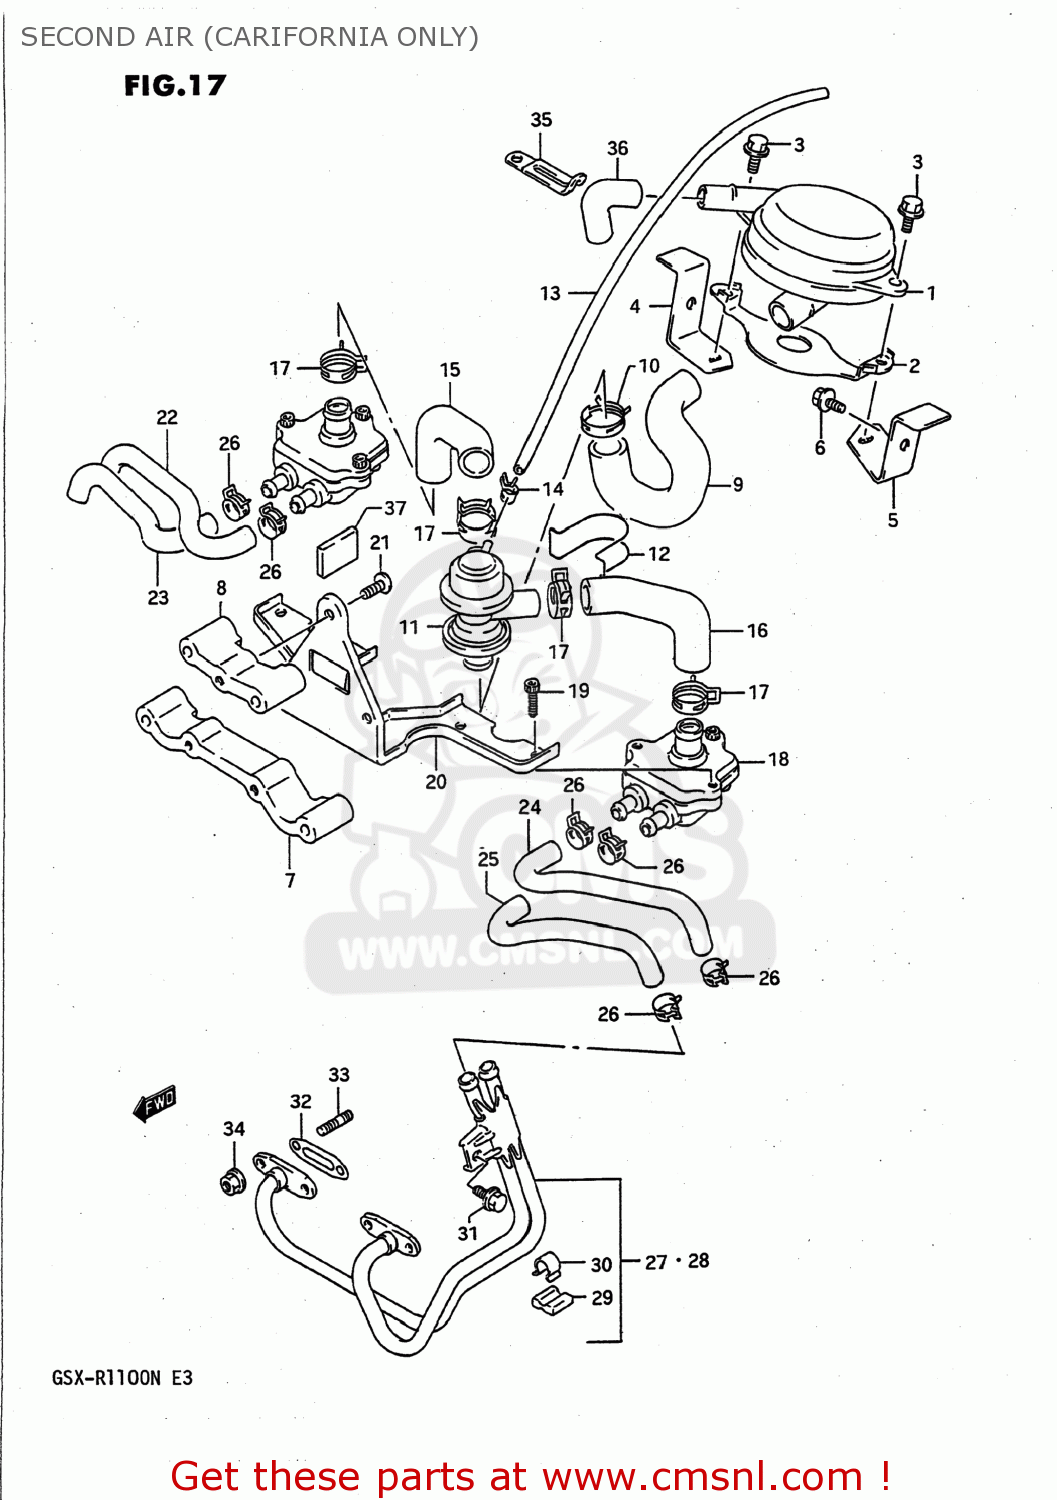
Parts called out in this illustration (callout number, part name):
1	CLEANER ASSEMBLY,SECOND AIR
2	HOLDER,SECOND AIR CLEANER
3	BOLT
4	BRACKET,SECOND AIR CLEANER
5	BRACKET,SECOND AIR CLEANER
6	BOLT
7	SPACER,SECOND AIR BRACKET,LOWER
8	SPACER,SECOND AIR BRACKET,UPPER
9	HOSE,SECOND AIR NO.3
10	CLIP
11	VALVE ASSEMBLY,AIR SWITCH
12	CLAMP,SWITCHING VALVE
13	HOSE
14	CLAMP
15	HOSE,SECOND AIR NO.2,RIGHT
16	HOSE,SECOND AIR NO.2,LEFT
17	CLIP
18	VALVE ASSY,2ND AIR REED
19	BOLT
20	BRACKET,SECOND AIR VALVE
21	SCREW
22	HOSE,SECOND AIR NO.1,RIGHT,INLET
23	HOSE,SECOND AIR NO.1,RIGHT,OUTLET
24	HOSE,SECOND AIR NO.1,LEFT,INLET
25	HOSE,SECOND AIR NO.1,LEFT,OUTLET
26	CLIP
27	PIPE ASSEMBLY,SECOND AIR,RIGHT
28	PIPE ASSEMBLY,SECOND AIR,LEFT
29	(CA) CUSHION
30	(CA) CLIP,SECOND AIR PIPE
31	BOLT 6X12
32	GASKET,SECOND AIR PIPE (NAS)
33	STUD BOLT
34	NUT 6MM
35	CLAMP
36	(CA) HOSE,SECOND AIR CLEANER
37	CUSHION
